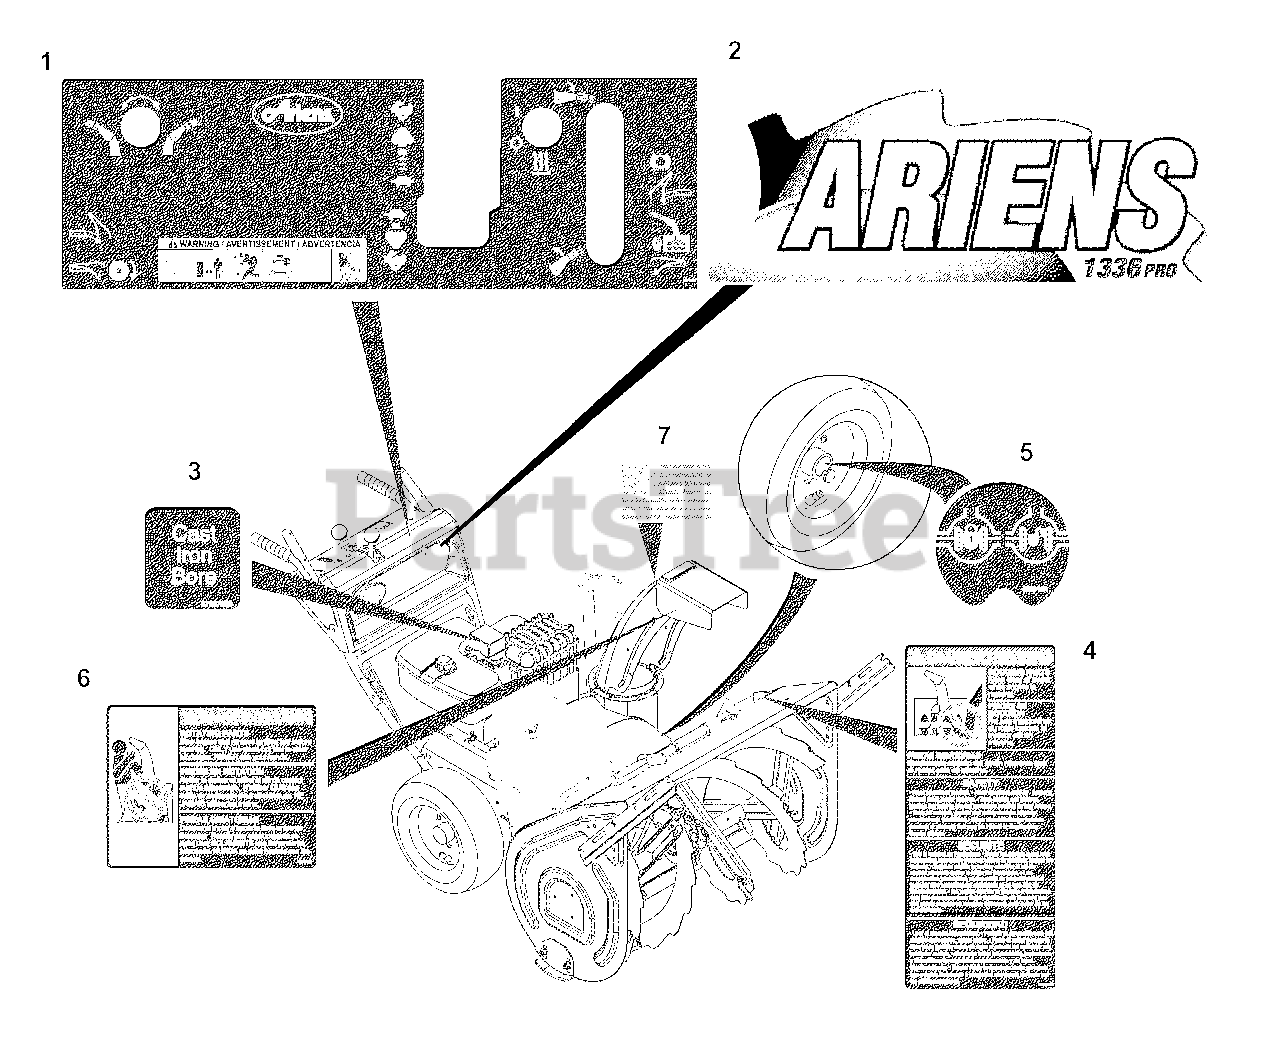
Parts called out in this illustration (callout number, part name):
1	DECAL, CONTROL - 1336
2	DECAL, DASH - 1336
3	DECAL - CAST IRON BORE
4	DECAL, DANGER
5	DIFFERENTIAL LOCK DECAL
6	DECAL, DANGER - ROT. PARTS
7	DECAL, AMERICAN FLAG
